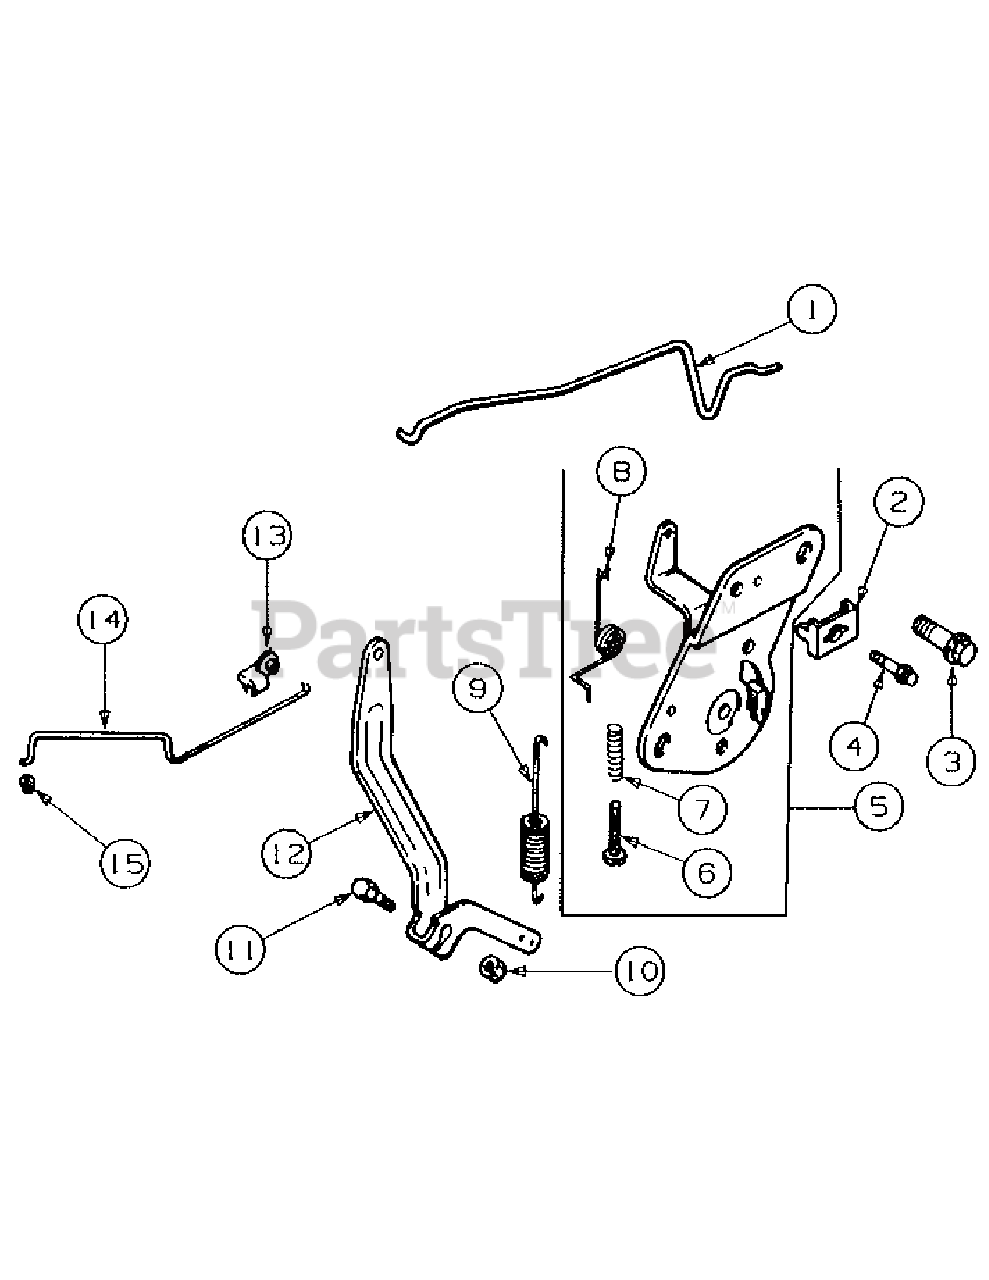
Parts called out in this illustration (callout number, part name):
1	Linkage, Choke
2	Clamp, Cable
3	Screw, Cable Clamp
4	Screw, Hex hd, M6 x 1.0 x 16
5	Control, Speed Ass'y
7	Spring, Speed Control
8	Spring, Choke Return
9	Spring Governor
10	Nut, Governor Arm,M6 x 1.0 x 25
11	Screw, Governor Arm, M6 x 1.0 x 25
12	Lever, Gobernor
14	Linkage, Throttle
